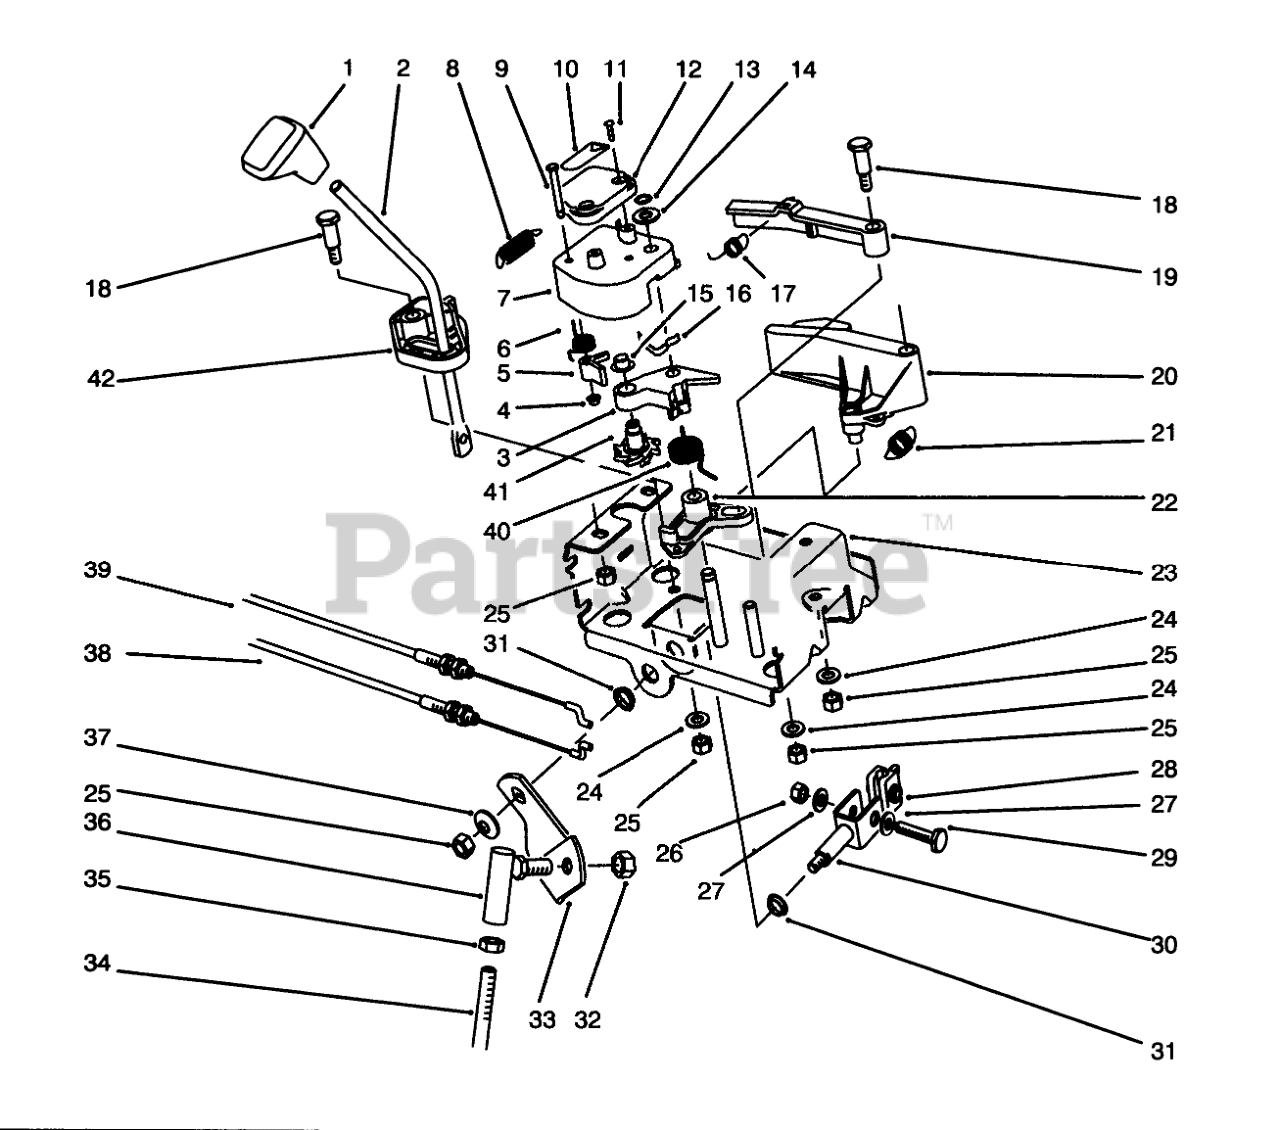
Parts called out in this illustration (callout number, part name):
1	KNOB-SHIFT
2	ROD-SHIFT
3	LEVER-WHEEL, INDEX
4	NUT-PUSH
5	TANG-INDEX
6	SPRING-TORSION
7	LATCH-LEVER
8	SPRING-EXTENSION
9	PIN-TANG
10	DECAL
11	SCREW-PPH
12	COVER-LATCH
13	RING-RETAINING
14	WASHER-THRUST
15	RETAINER-PUSH ON
16	SPRING-FLAT
17	SPRING-EXTENSION
18	SCREW-SHOULDER
19	LEVER-LOCKOUT
20	LEVER-REVERSE
21	SPRING-EXTENSION
22	LEVER-REVERSE, SWITCH
23	Frame-Control
24	WASHER-PLAIN
25	NUT-LOCK, NI
26	NUT-LOCK, NI
27	WASHER-FLAT
28	RETAINER-ROD, SHIFT
29	SCREW-HH
30	CLEVIS ASM
31	BUSHING
32	NUT-LOCK, NI
33	BRACKET-SHIFT
34	ROD-BENT SHIFT, LOWER
35	NUT-HJ
36	JOINT-BALL
37	WASHER-BELLEVILLE
38	CABLE-GEARBOX
39	CABLE-ARM, LATCH
40	SPRING-TORSION
41	WHEEL-INDEX
42	BASE-LOCKOUT
